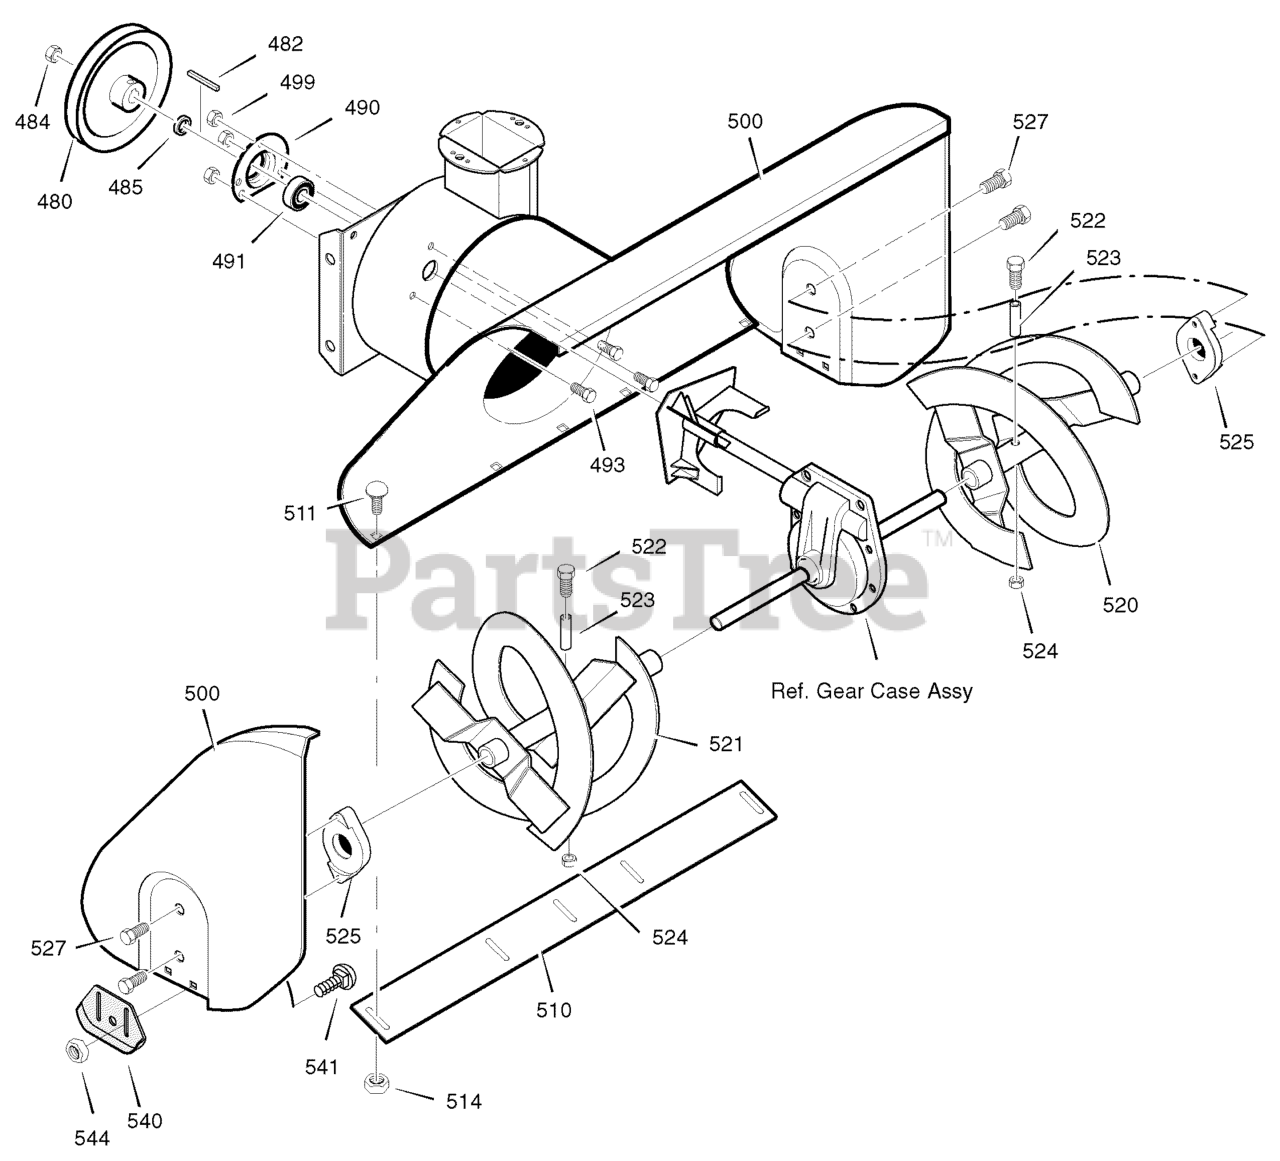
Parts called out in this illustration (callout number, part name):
480	PULLEY, 4L 8.40 OD.
482	KEY, SQUARE 3/16 X 3/4
484	NUT, .50-20 HEXWDFLLK
485	SPACER, FRICTION PULLEY
490	RETAINER, BALL BRNG
491	BEARING, BALL
493	BOLT, HEX 5/16-18X .50
499	NUT, 5/16-18 HEXWDFLLK
500	HOUSING, ASSY
510	BLADE, SCRAPER
511	BOLT, 5/16-18x0.75
514	NUT, 5/16-18
520	AUGER, ASSY, LH
521	AUGER, ASSY, RH
522	SCREW, 1/4-20X1.75
523	SPACER, SLEEVE
524	NUT, 1/4-20
525	BEARING, FLANGE
527	SCREW, 5/16-18 X .75
540	SKID, HEIGHT ADJUST
541	BOLT, 5/16-18 X .75
544	NUT, 5/16-18
